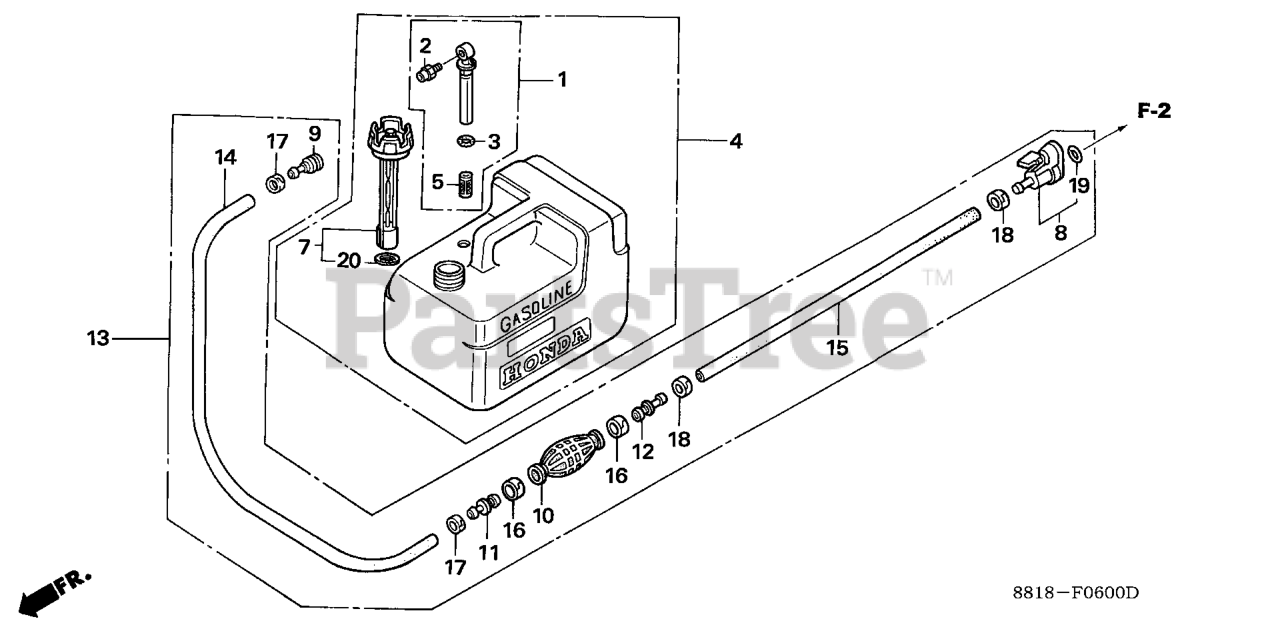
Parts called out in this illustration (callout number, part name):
1	JOINT ASSY., FUEL
2	FITTING, QUICK DISCONNECT Use from Frame SN 1205705.
3	O-RING Use from Frame SN 1300962.
4	TANK ASSY., FUEL
5	FILTER, FUEL
7	CAP, FUEL FILLER
8	CONNECTOR, FUEL *NH1* (BLACK)
8	CONNECTOR, FUEL *NH282MU* (OYSTER SILVER METALLIC-U)
9	CONNECTOR, FUEL (CONNECTOR TYPE)
10	BULB, PRIMER
11	VALVE, IN.
12	VALVE, OUTLET
13	TUBE, FUEL *NH1* (BLACK)
13	TUBE, FUEL *NH282MU* (OYSTER SILVER METALLIC-U)
14	TUBE, FUEL LONG (7.3X2000) (CONNECTOR TYPE)
15	TUBE, FUEL SHORT
16	BAND, TUBE CLIP (20MM)
17	BAND, TUBE CLIP (12.5MM)
18	BAND, TUBE CLIP (11MM)
19	O-RING (5.5MM)
20	GASKET, FUEL CAP
